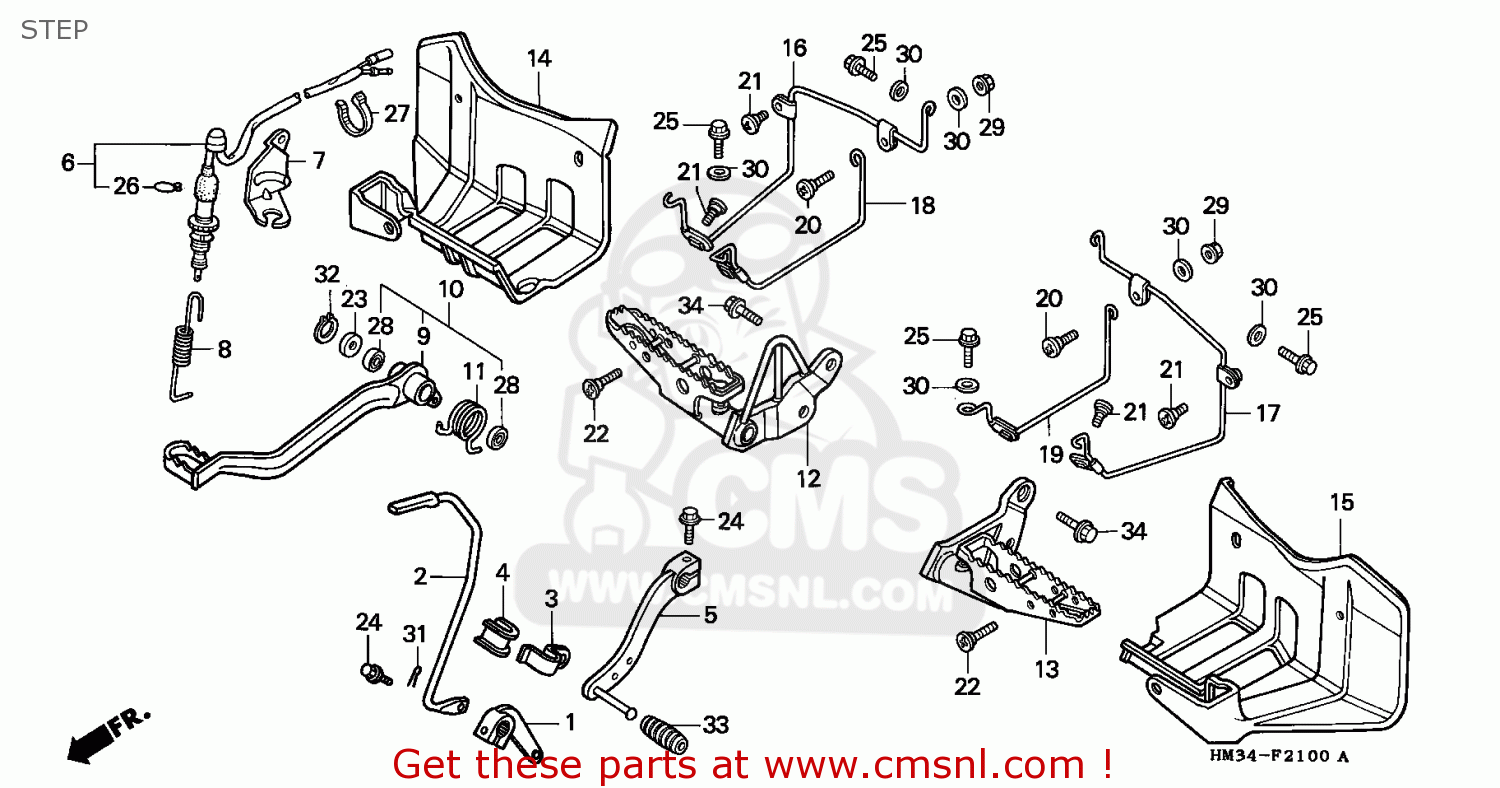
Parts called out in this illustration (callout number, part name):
1	ROD,RVS.SHIFT
2	ROD,RVS SHIFT
3	HOLDER,RVS ROD
4	BUSH,REVERSE ROD
5	PEDAL,GEAR CHANGE
9	PEDAL COMP.,BRAKE
11	SPRING,BRAKE PEDA
12	STEP COMP,R
13	STEP COMP.,L.
14	MUDGUARD,*NH154R*
15	MUDGUARD,*NH154R*
16	STAY,R.MUDGUARD O
17	STAY,L.MUDGUARD O
18	STAY,R.MUDGUARD I
19	STAY,L.MUDGUARD I
20	SCREW,MUDGUARD,6X
21	SCREW,MUDGUARD
22	SCREW,SPECIAL 6MM
23	WASHER,17.5MM
24	BOLT,FLANGE,6X20
25	BOLT,FLANGE,6X16
28	SEAL,DUST 17X23X3
30	WASHER,PLAIN,6MM
31	PIN COTTER 2.0MM
32	CIR-CLIP,EX, 17MM
33	RUB.,CHANGE PEDAL
34	BOLT,FLANGE,10X35
